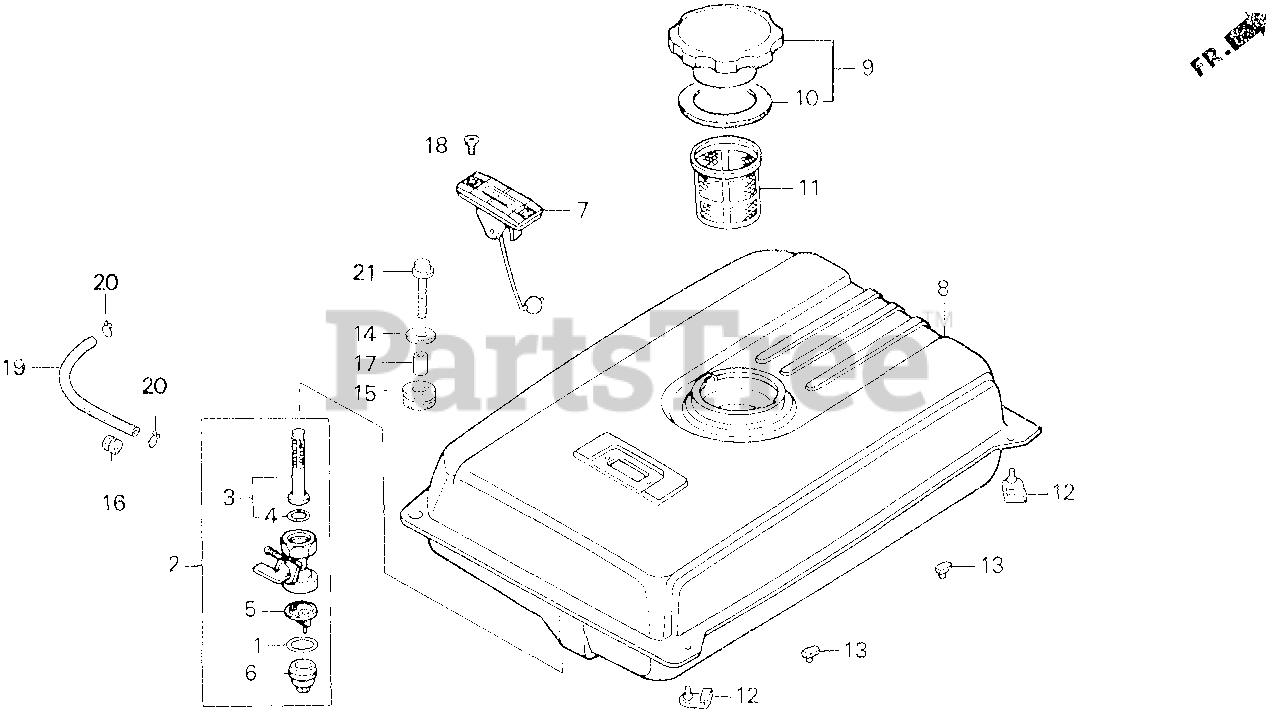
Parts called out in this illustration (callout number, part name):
1	GASKET, FUEL STRAINER CUP
2	PETCOCK ASSY.
3	SCREEN, FUEL STRAINER
4	O-RING (9X1.3)
5	FILTER, CUP
6	CUP, FUEL STRAINER
7	METER ASSY., FUEL
8	TANK, FUEL *T68* (TSURUI BLUE)
9	CAP, FUEL TANK
10	GASKET, FUEL FILLER CAP
11	FILTER, FUEL
12	RUBBER, TANK MOUNTING
13	STOPPER, DISCHARGE GUARD
14	WASHER, TANK RUBBER
15	CUSHION, TANK RUBBER
16	RUBBER, FUEL TUBE
17	COLLAR, TANK RUBBER
18	SCREW, FLAT (5X10)
19	BULK HOSE, FUEL (4.5X3000) (4.5X260)
20	CLIP, TUBE (B8)
21	BOLT, FLANGE (6X22)
